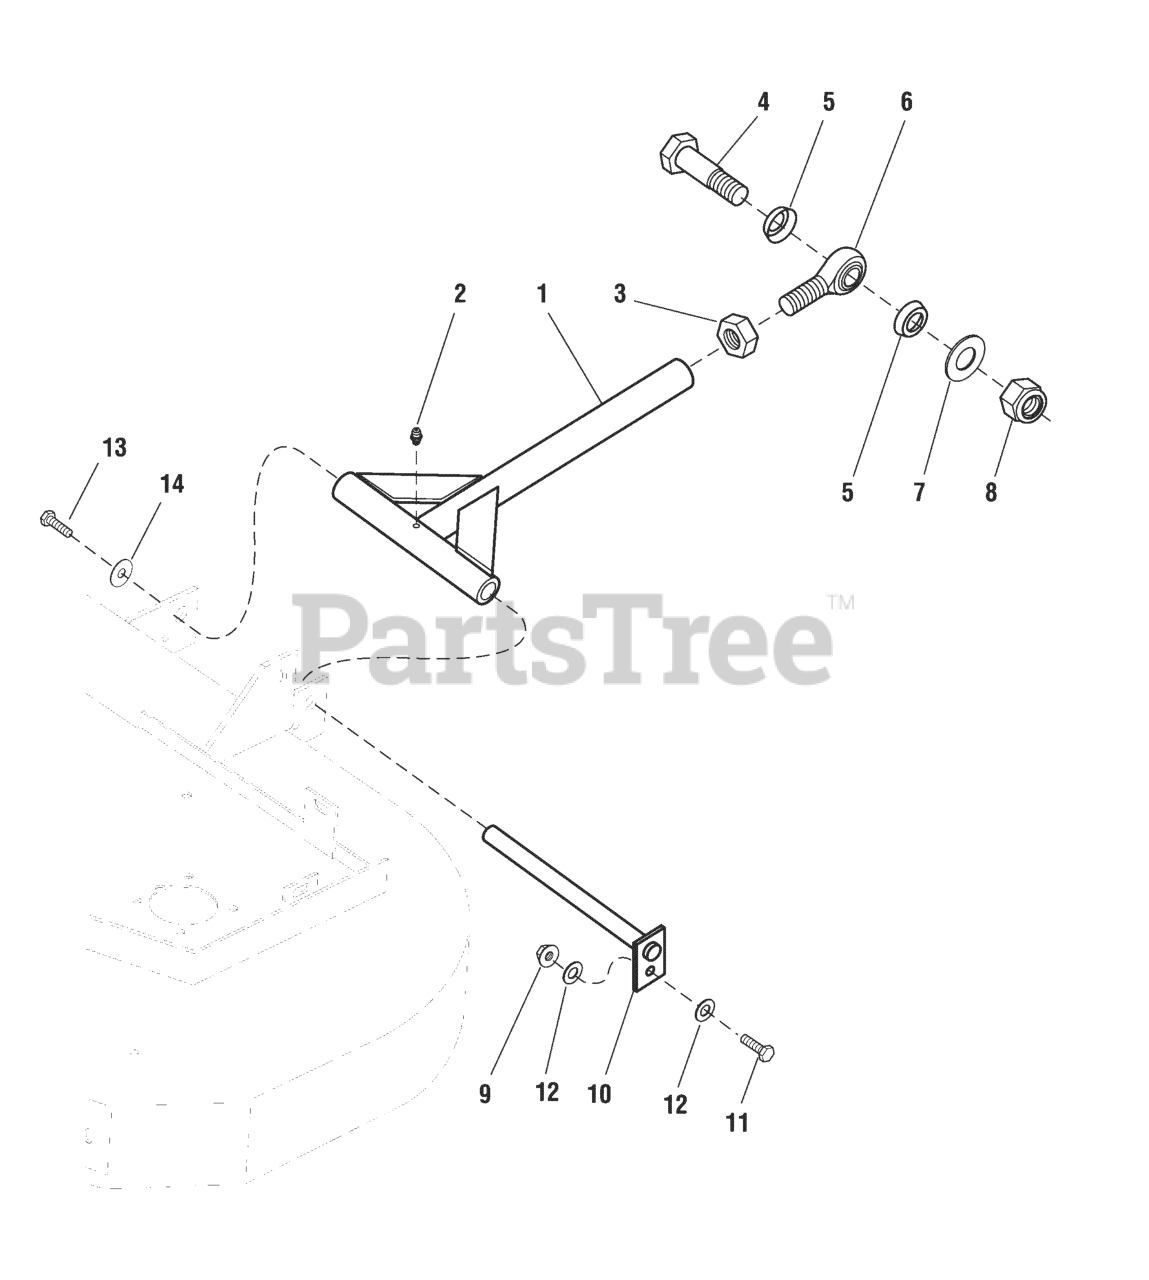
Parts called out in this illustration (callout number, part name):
1	ASSM, DECK PUSHER BAR
2	GREASE FITTING
3	NUT, 3/4-16 Hex Jam
4	BOLT, 3/4-16 x 3
5	ROD END SEAL
6	BALL JOINT, 3/4-16 Male
7	WASHER, 3/4 SAE
8	NUT, 3/4-16 Hex Nylon Lock
9	NUT, 3/8-16 HEX NYLON LOCK
11	BOLT, 3/8-16 X 1-1/4" GD5 CZ
12	WASHER, 3/8 SAE
13	BOLT, 3/8-16 X 1" GD5 CZ
14	WASHER, .390 X 1.50 X .109 YZ
